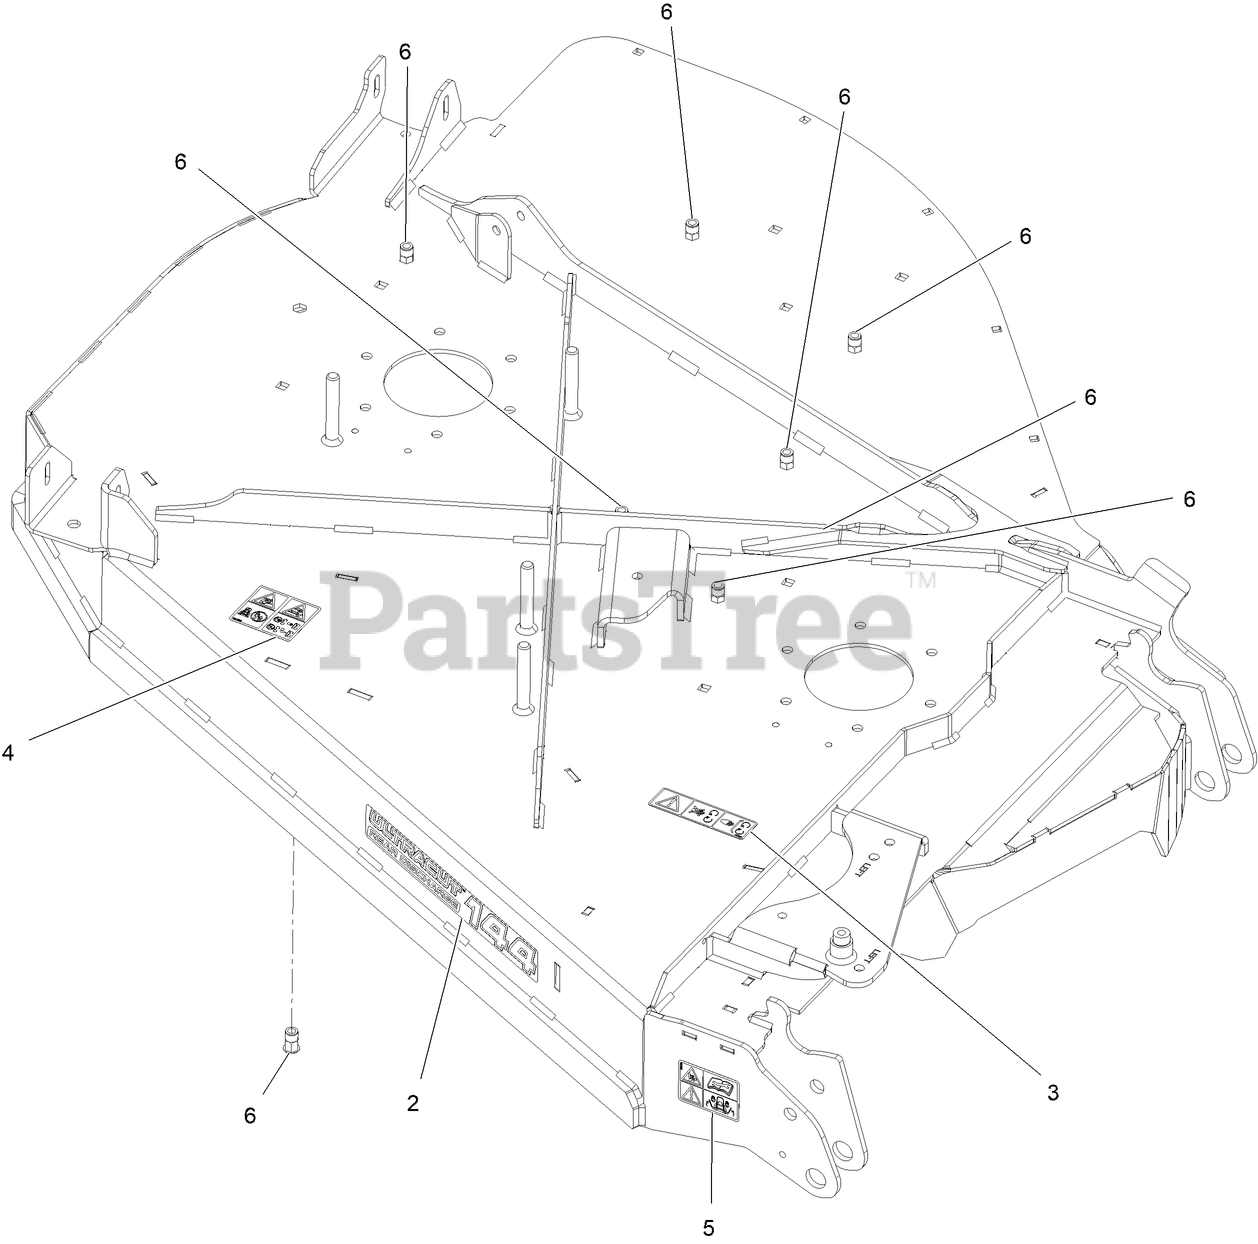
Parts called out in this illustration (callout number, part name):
2	DECAL-ULTRACUT 144
3	DECAL-COVER, MISSING
4	DECAL-DANGER, THROWN OBJECT
5	DECAL-WARNING, PINCH POIN
6	NUT-CLINCH,HEX
